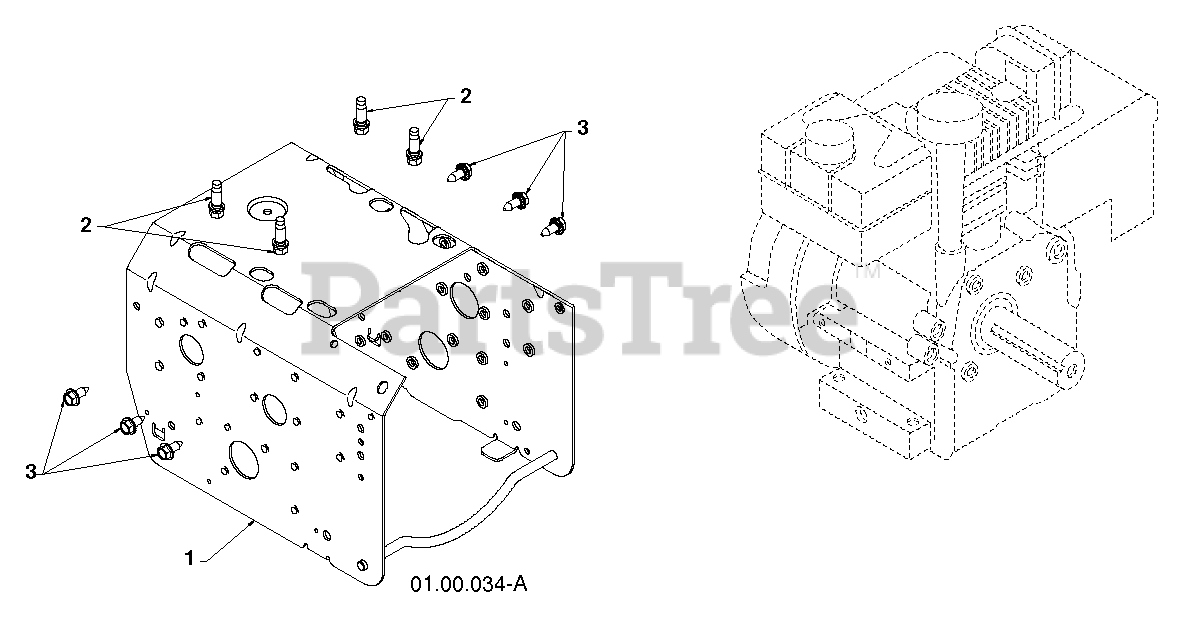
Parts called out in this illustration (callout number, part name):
1	FRAME.WELD.CHAIN.PNT.YELLOW
2	BOLT 3/8-16X1-1/8
3	BOLT.HEX.HD.WASHER.5/16-18X.75
